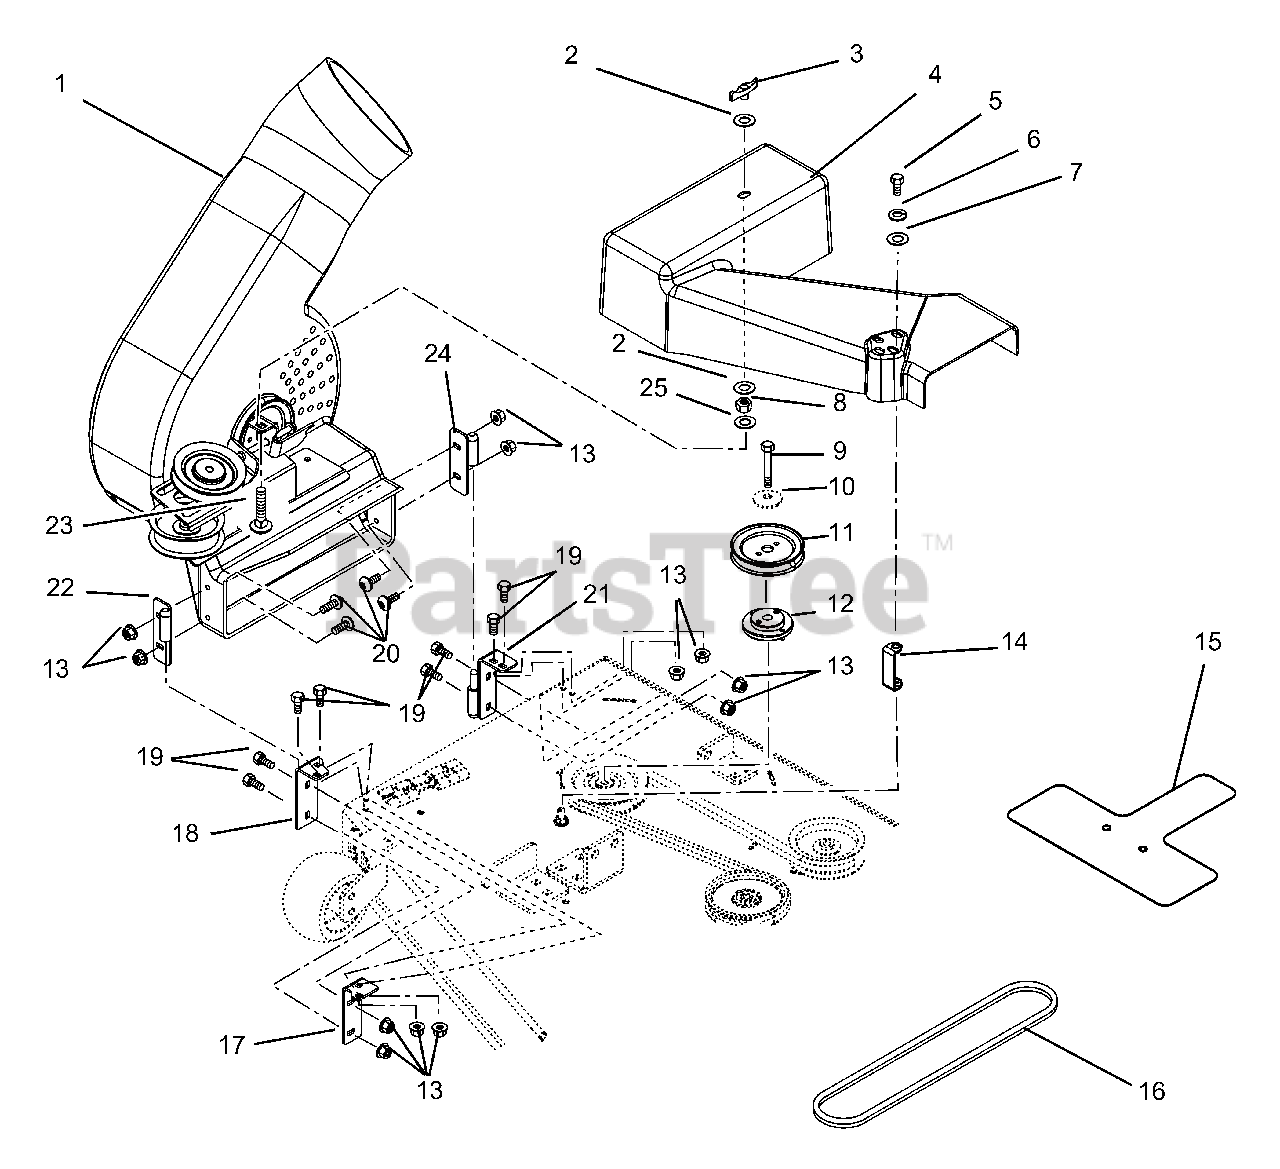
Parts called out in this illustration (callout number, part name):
1	Housing, Blower
2	Washer-Flat-Steel.38 x 1.50 x .062
3	Knob- Wing .312-18
4	Belt Cover
5	Bolt-Hex .38-16 x .75 - Grade 5
6	Washer-Locking .38 x .094 Regular
7	Washer-Flat-Steel .438 x 1.00 x .083
8	Nut-Jam .312-18
9	Bolt-Hex .38-16 x 1.75 - Grade 8
10	Washer, Cupped, .375
11	Sheave, 3.00 Diameter
11	Sheave, 4.00 Diameter
12	Assembly, Sheave Adapter
13	Nut-Locking-Top-Flange .25-20
14	Spacer, Cover
15	Guard, Finger
16	V-Belt
17	Bracket, Front
18	Weldment, Front Mount Bracket
19	Bolt-Hex .25-20 x .75 - Grade 5
20	Screw-Machine .25-20 x .75
21	Weldment, Rear Mount Bracket
22	Weldment, Housing Mount Right Hand
23	Bolt-Round Head Square Neck .31-18 x 1.50
24	Weldment, Housing Mount Left Hand
25	Washer-Flat-Steel .312 x .734 x .065
